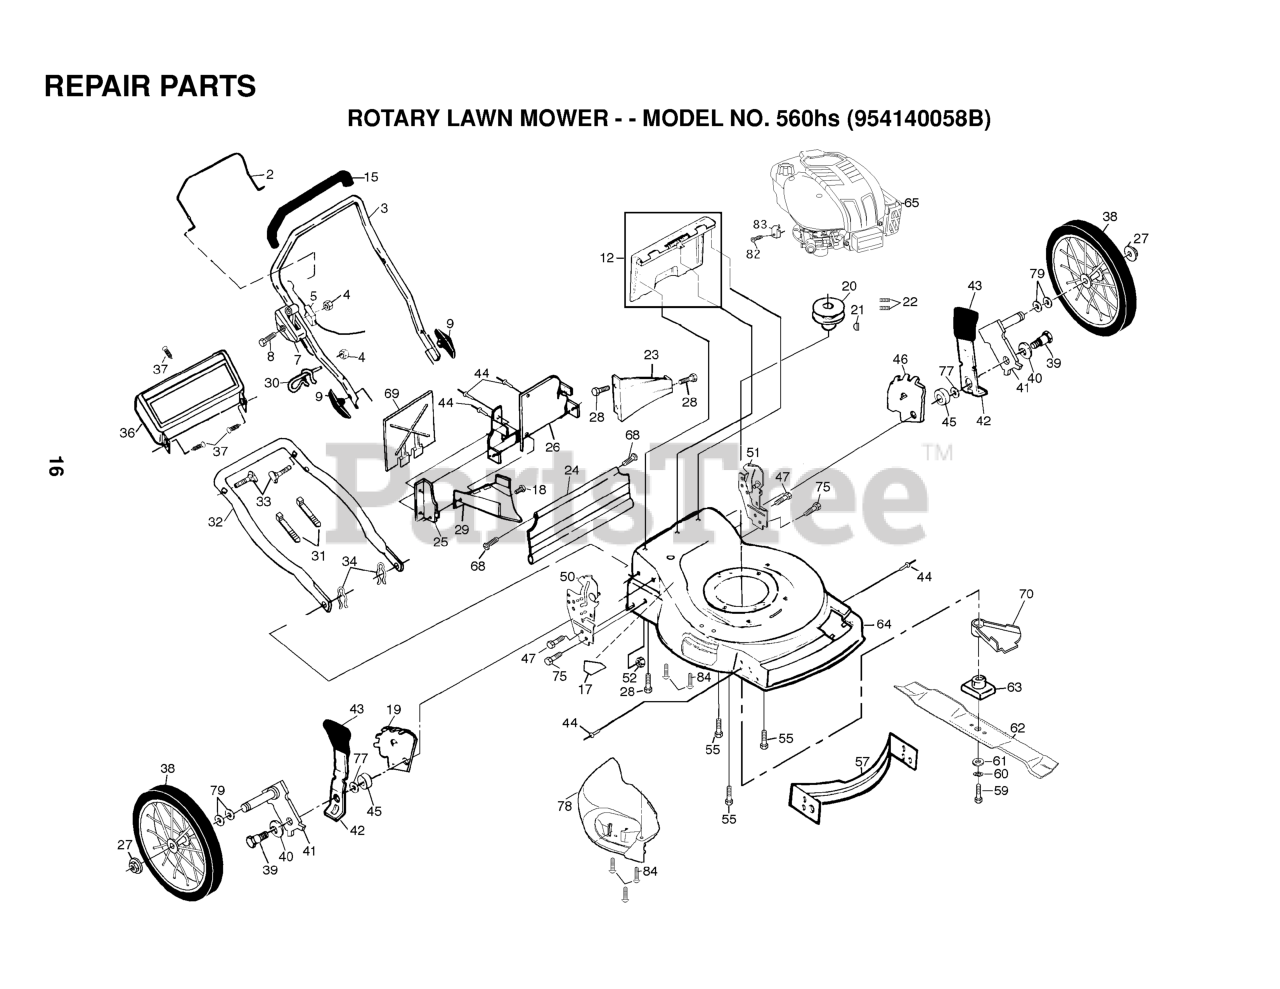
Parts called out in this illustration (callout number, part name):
2	BAIL.CONTROL.WIRE.STD.COMF.BLK
3	UPPER HANDLE
4	NUT
5	CABLE ASSEMBLY
7	THROTTLE CONTROL
8	SCREW 1/4-20 X 2.12
9	HANDLE KNOB
12	KIT.DOOR.REAR.22.STEEL.BLACK
15	GRIP.HANDLE.FOAM
17	DECAL HYT
18	SCREW.HXTAP.10-24
19	WHL ADJ BRKT LF/RR
20	ENGINE.PULLEY.FWG
21	HI PRO KEY PM WSL
23	REAR BAFFLE
24	REAR SKIRT
25	SIDE BAFFLE
26	BACK PLATE
27	HEX FLANGE LOCKNT
29	DISCHARGE BAFFLE
30	ROPE GUIDE
31	TIE GUIDE
32	HANDLE, LOWER
33	HANDLE BOLT
34	HAIRPIN COTTER
36	TRIM PLATE
38	WHEEL TIRE PM
39	BOLT
40	WASHER
41	AXLE ARM ASSEMBLY (REAR)
42	SELECTOR SPRING
43	SELECTOR KNOB
44	RIVET BLIND
45	RP SPACER HT ADJ
46	WHL ADJ BRKT RF/LR
47	SELF-TAPPING SCREW 5/16-18X3/4
50	BRACKET
51	BRACKET
52	LOCKNUT PM
55	BOLT 3/8-16X1-1/8
57	BAFFLE
59	SCREW, HEX HD 3/8-24 X 1-3/8
60	LOCKWASHER
61	WASHER,HARDEN
63	BLADE ADAPTOR
64	DECK SHELL
68	HINGE SCREW
69	MULCHER PLATE
70	DEBRIS SHIELD
77	WASHER.FLAT.1/2
78	QUICK TRIM DOOR
79	WAVE WASHER
82	SCREW.HEX.HEAD.WASHER.10-16
83	WASHER
84	SCREW.PAN.HEAD.#10
